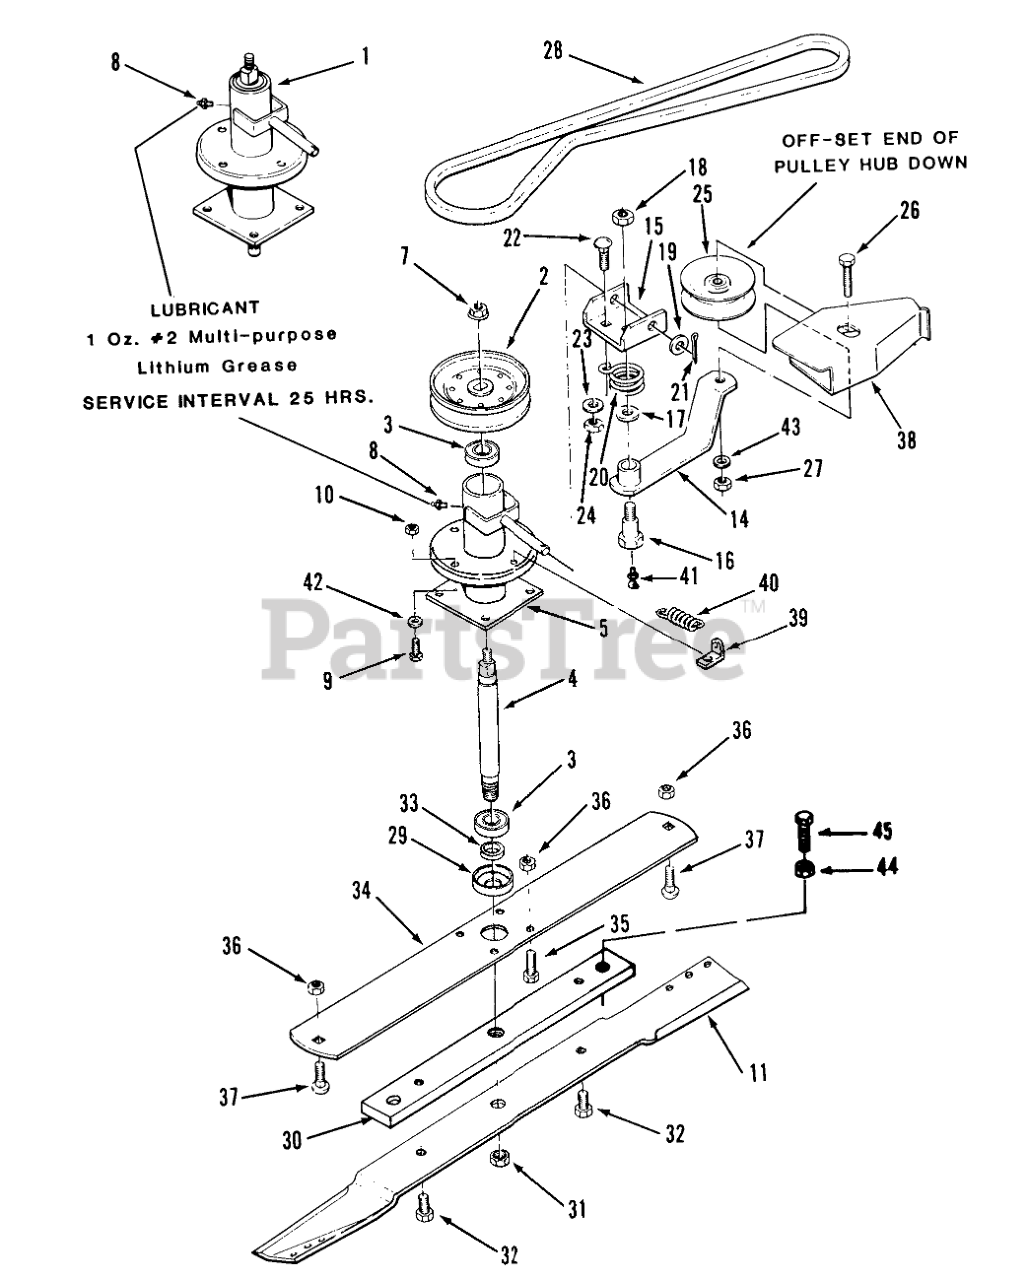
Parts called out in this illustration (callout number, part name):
1	Spindle Complete (includes items 3, 4, 5 & 8)
2	PULLEY SPINDLE
3	BALL BEARING
4	SHAFT SPINDLE
5	ASS'Y-BLADE HOUSI R
7	NUT 3/8-24 WHIZLOCK
8	Zerk
9	Bolt
10	Nut
11	Blade
14	ASSY LEVER R
15	CHANNEL PIVOT R
16	SHOULDER BOLT
17	WASHER
18	NUT-JAM(7/16-14)
19	Washer
20	SPRING-TORSION
21	Cotter Pin
22	Bolt
23	Washer
24	NUT
25	PULLEY IDLER R
26	Bolt
27	NUT
28	BELT-V, LOWER PTO
29	CUP SPINDLE
30	BAR-BLADE R
31	Nut 5/8 UNF
32	HEX BOLT 1/2-13X3/4
33	SPACER-BLADE
34	PLATE SUPPORT R
35	BOLT
36	NUT
37	Carriage Bolt 3/8-16 X 3/4
38	COVER BELT R
39	CLIP - SPRING
40	SPRING-EXTENSION
41	ZERK 90DEGREE
42	Lockwasher
43	WASHER
44	NUT-HEX, JAM
45	Bolt
